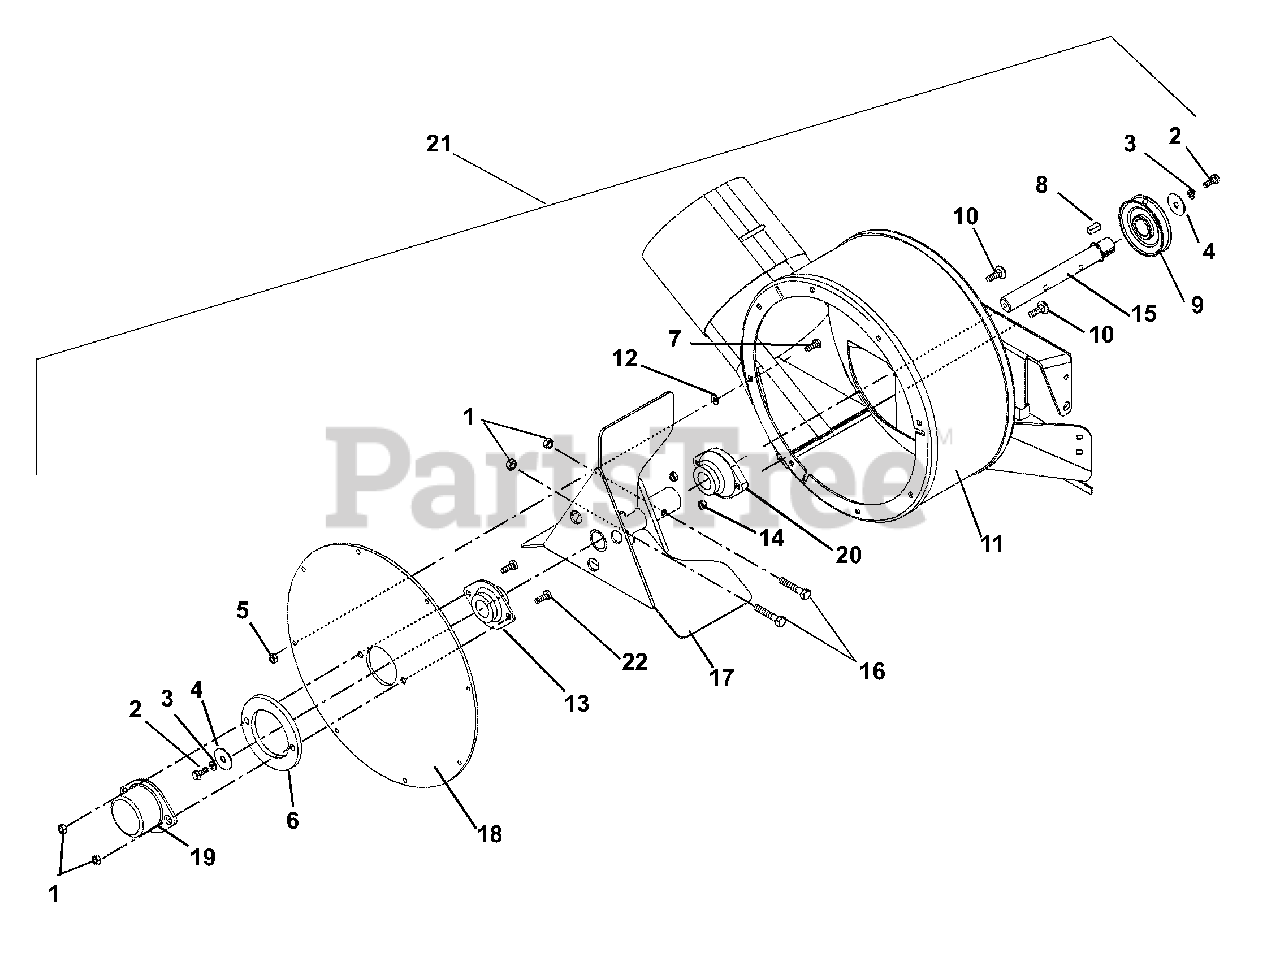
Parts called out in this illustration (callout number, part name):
1	Nut-Locking-Center .31-18
2	Bolt-Hex .25-20 x .75 Grade 5
3	Washer-Locking .25 x .062 Regular
4	Washer-Flat-Steel .265 x 1.370 x .179
5	Nut-Locking-Center .25-20
6	Plate, Retainer
7	Bolt-Round Head Square Neck .25-20 x .50
8	Key-Square .25 x .25 x 1.00
9	Pulley-V 3.50 x 1.004 w/key
10	Bolt-Round Head Square Neck .31-18 x 1.00
11	Weldment, Blower Housing
12	Nut, Push .25 x .50
13	Bearing-2 Bolt x 1.00 Shaft
14	Nut-Locking-Top-Flange .31-18
15	Shaft-Impeller
16	Bolt-Hex .31-18 x 1.75 Grade 5
17	Weldment, Bagger Impeller
18	Cover-Bearing Support
19	Cover-Bearing
20	Bearing, Flange w/Set Screw 1.00 ID
21	Assembly, Blower Housing
22	Bolt, Hex .31-18 x 1.0
